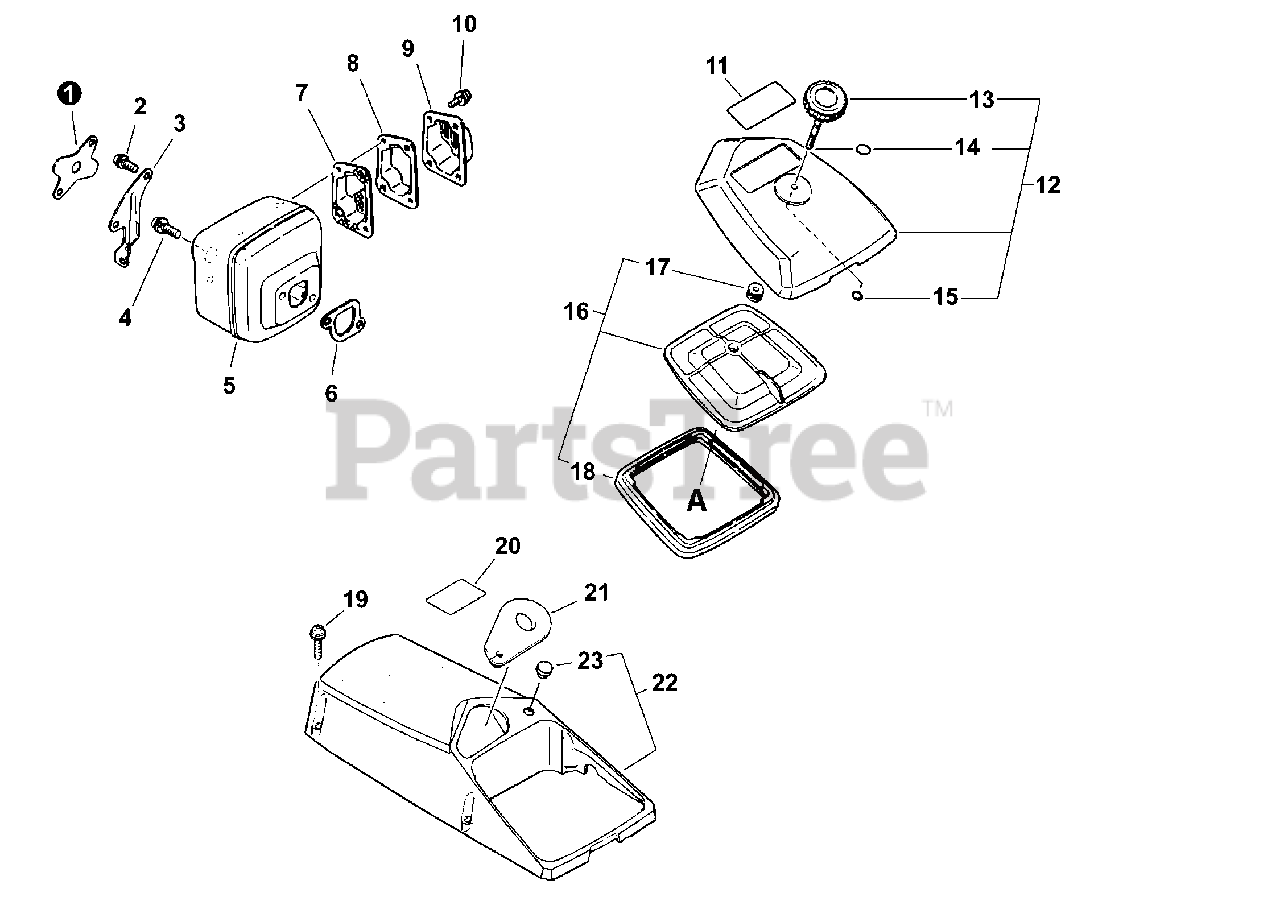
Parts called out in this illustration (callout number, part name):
1	COVER, MUFFLER
2	BRACKET, MUFFLER
3	BOLT 5×14
4	BOLT 6×20
6	GASKET, MUFFLER
7	HOLDER, SCREEN
8	SCREEN, MUFFLER
9	LID, MUFFLER
10	BOLT 4×10
11	LABEL, MODEL
12	AIR CLEANER COVER SET
13	THUMB NUT
14	O-RING 10
15	O-RING 3
16	FILTER, AIR W/SEAL
18	SEAL, CLEANER
19	BOLT 5×20
20	LABEL, KICK BACK
21	PLATE, GUIDE
22	COVER, CYLINDER - Gray
22	COVER, CYLINDER - Orange
